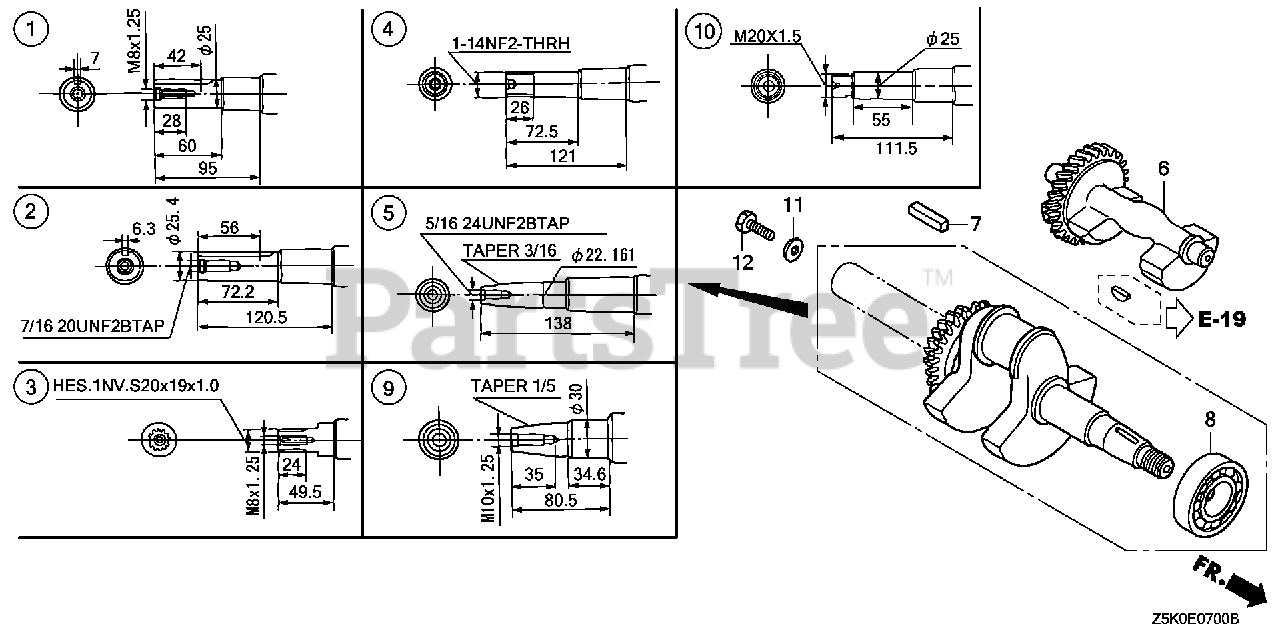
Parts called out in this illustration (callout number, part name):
2	CRANKSHAFT
6	WEIGHT, BALANCER
7	KEY (6.3X6.3X43)
8	BEARING, RADIAL BALL (6206 SH)
